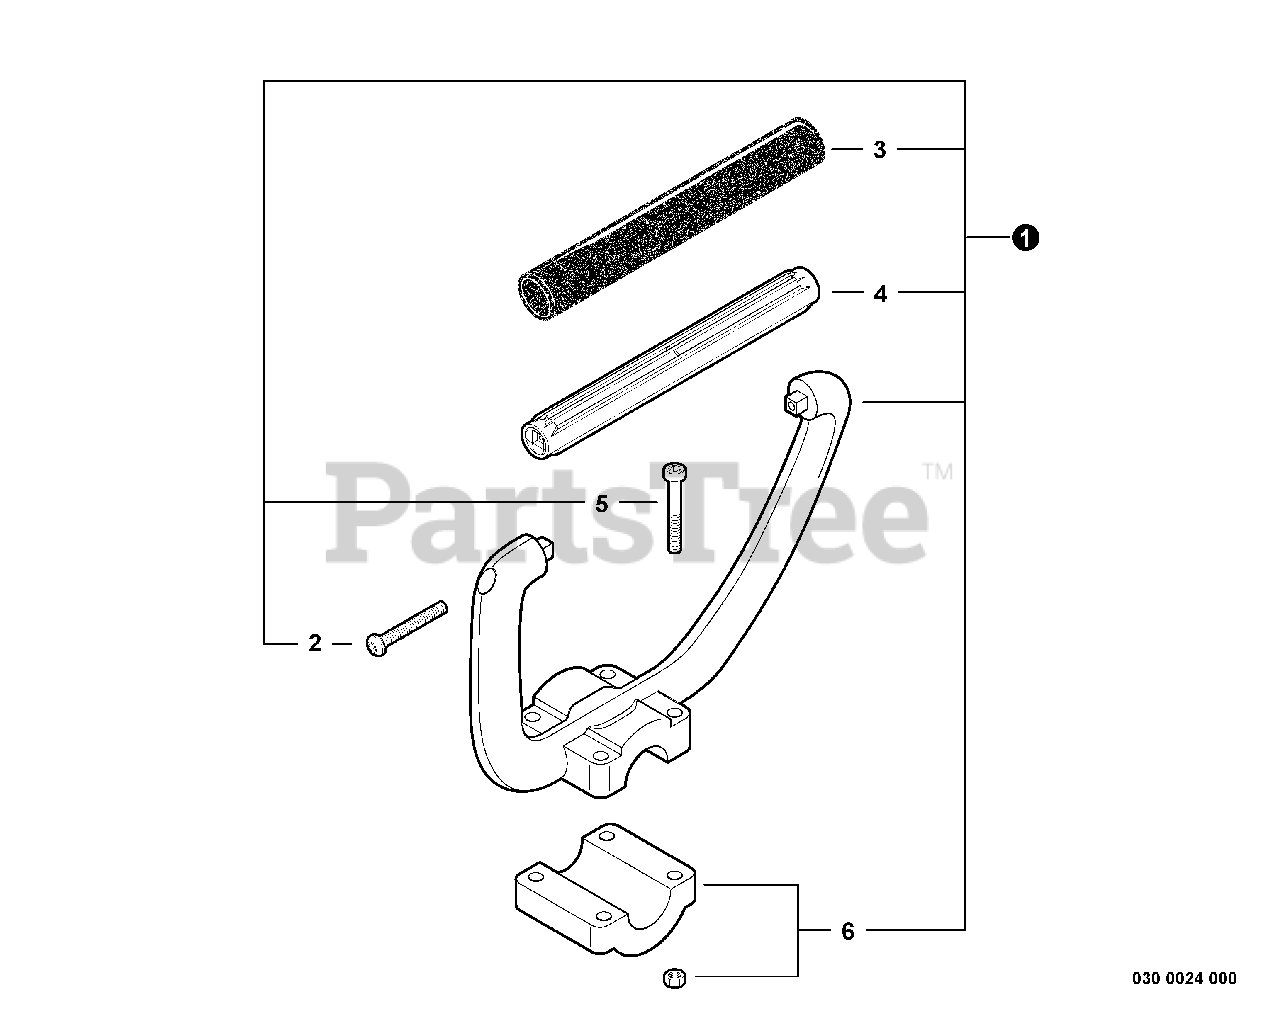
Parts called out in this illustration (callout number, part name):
1	HANDLE ASSY - SUPPORT
2	BOLT, TORX 5×35
3	GRIP, HANDLE
5	SCREW 5×35
6	BRACKET, HANDLE
